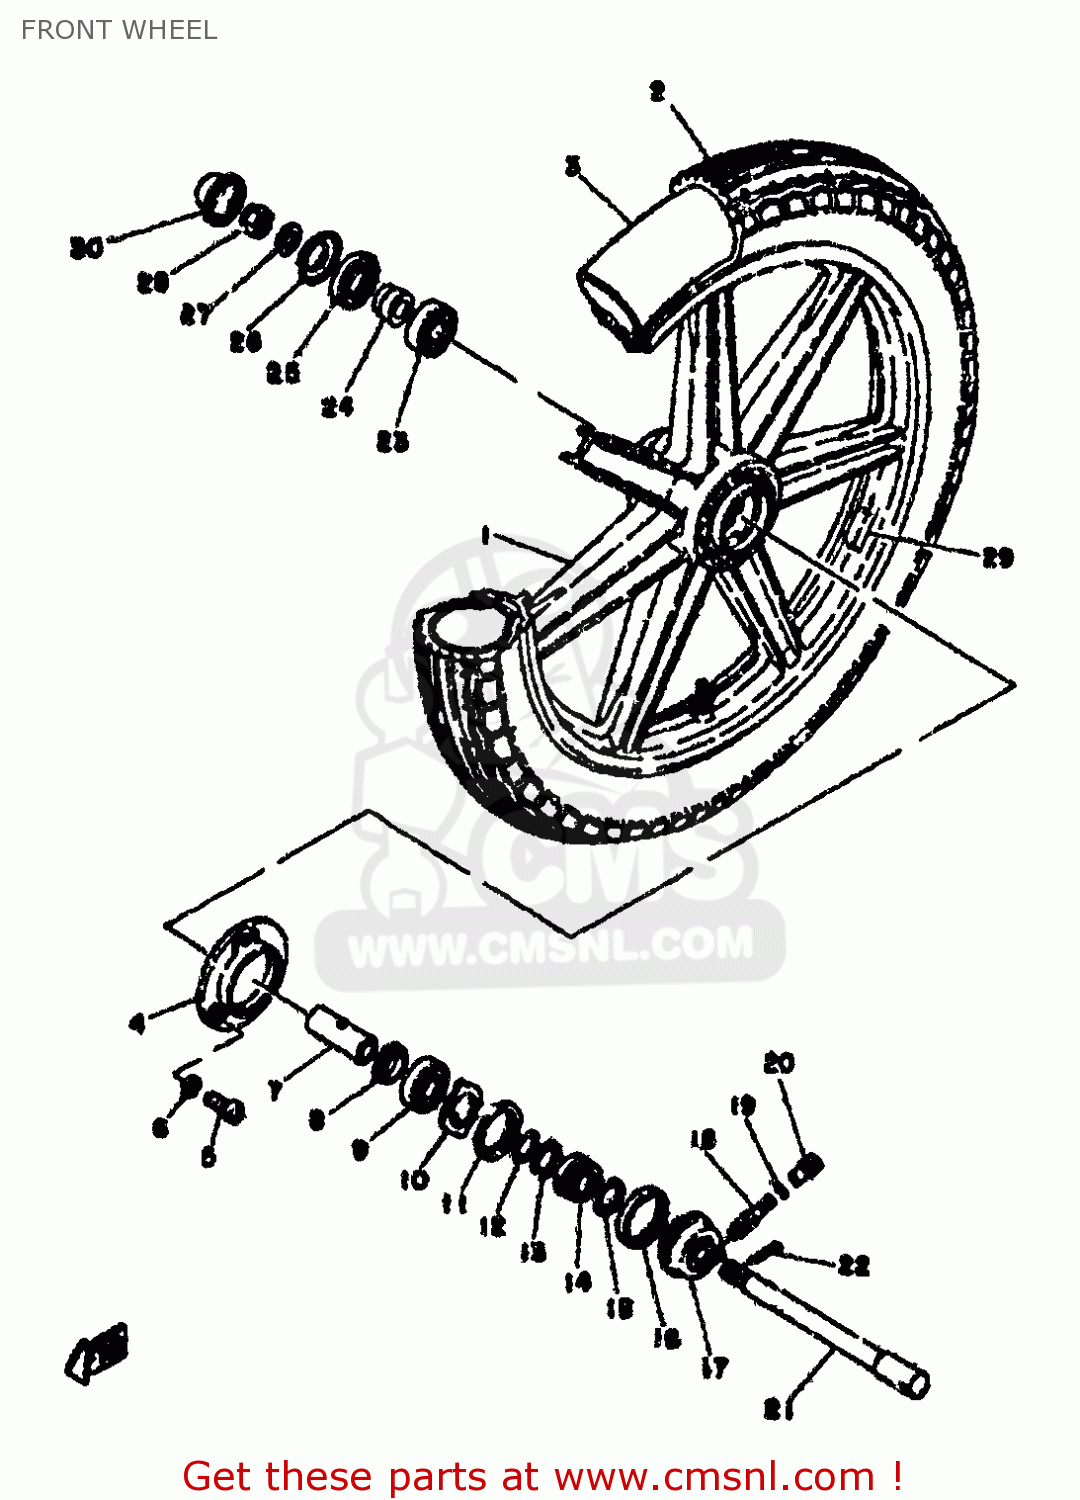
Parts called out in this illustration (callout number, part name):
1	CAST WHEEL, FRONT (1.85-19) ~102259 CANADA
2	TIRE (5A8)
3	TUBE (1V2)
4	COVER, HOUSING
5	SCREW PAN HEAD
6	WASHER, SPRING
7	SPACER 351251170000
8	FLANGE, SPACER
9	BRG,R-B 6303Z 47MM 116G KY
10	CLUTCH, METER (371,447)
11	RETAINER, CLUTCH (371,447)
12	RING, STOP (371,447)
13	WASHER PLATE 341251470000
14	GEAR, DRIVE (371,447)
15	WASHER PLATE 152172260000
17	HOUSING, GEAR UNIT (371,447)
18	GEAR,METER
19	SHIM, ROD (B)
20	BUSHING
21	SHAFT,WHEEL
22	PIN,COTTER
23	BRG,R-B 6303Z 47MM 120G NT
24	COLLAR 341251830000
25	OIL SEAL (28X47X7-102)
26	COVER, DUST (447)
27	WASHER (521)
28	NUT, CASTLE (214-25182-01)
29	BALANCER, WHEEL (20G)
